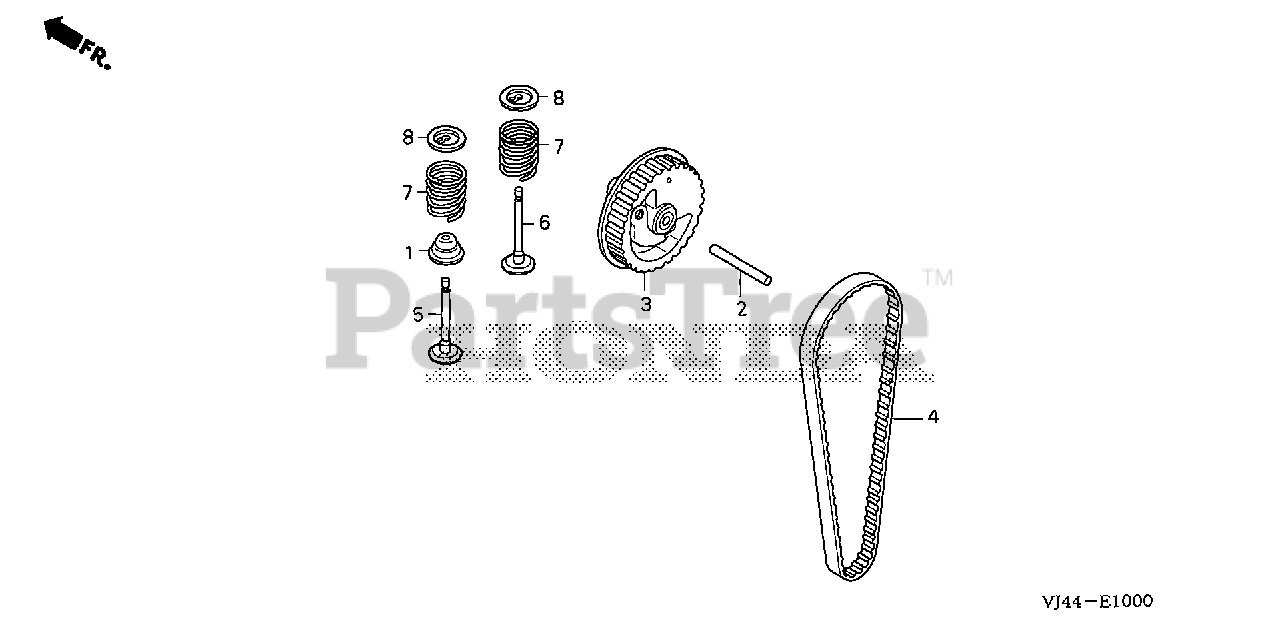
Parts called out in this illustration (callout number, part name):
1	SEAL, VALVE STEM
2	ROLLER (4X29.8)
3	PULLEY, CAMSHAFT
4	BELT, TIMING (71ZU5 G-310)
5	VALVE, IN. (EI)
6	VALVE, EX. (EE)
7	SPRING, VALVE
8	RETAINER, VALVE SPRING
